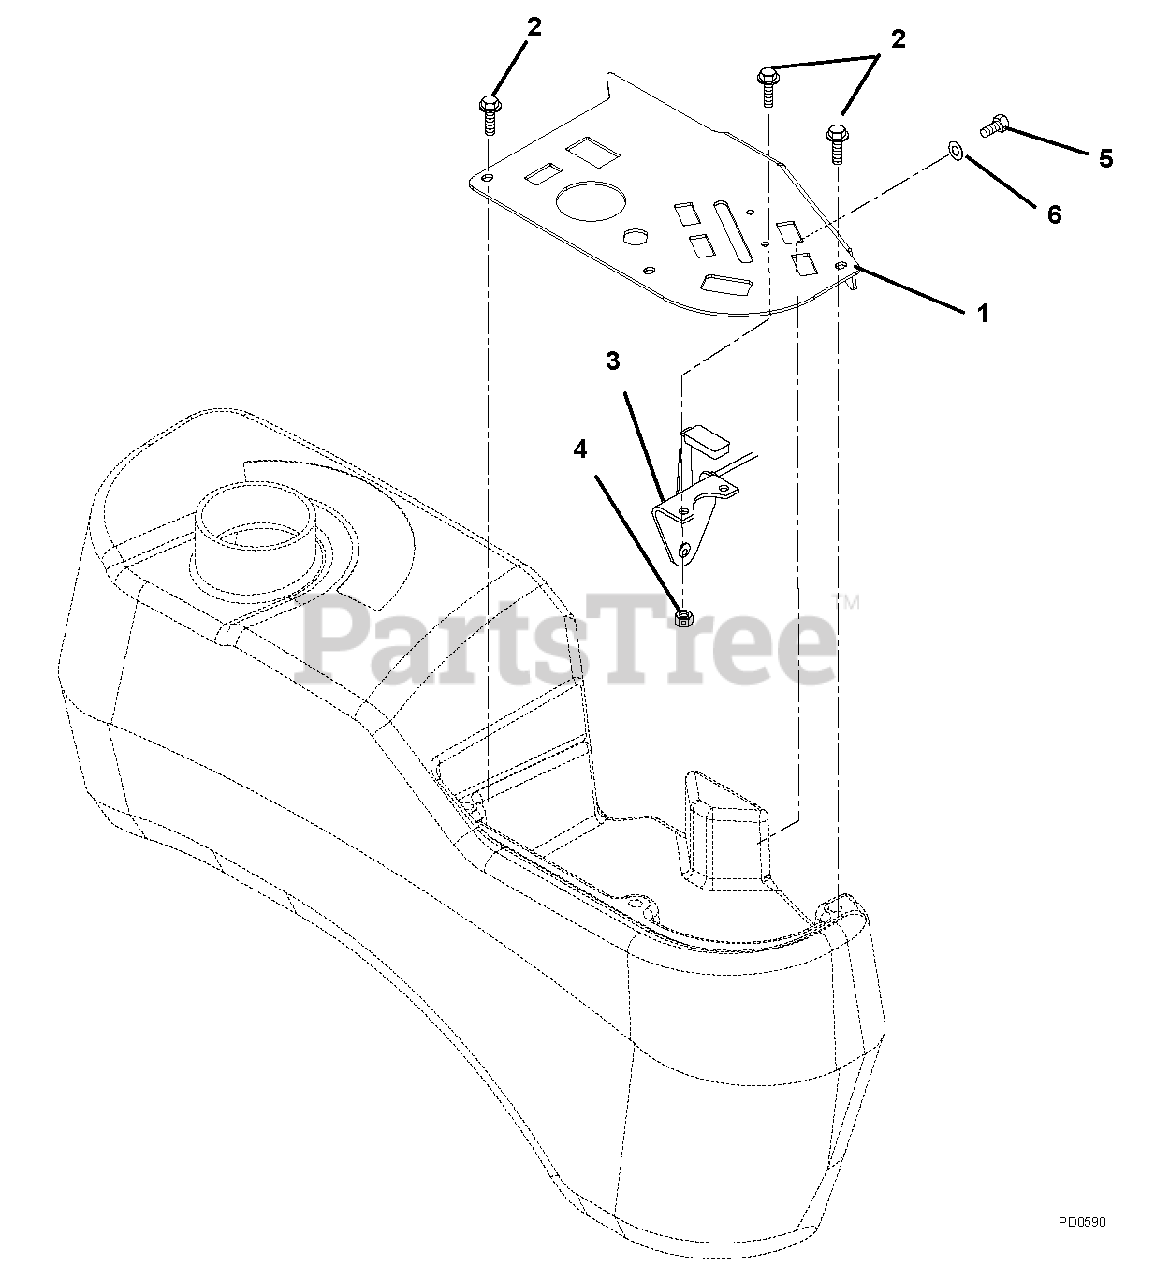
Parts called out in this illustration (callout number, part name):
1	Panel-Control
2	Screw-Machine 10-24 x .50 Hex Washer Head Stainless
3	Throttle, Control
4	Nut-Locking-Nylon 10-24 With Insert
5	Bolt-Hex .31-18 x .75 Grade 5
6	Washer-Flat-Steel .38 x .875 x .083
